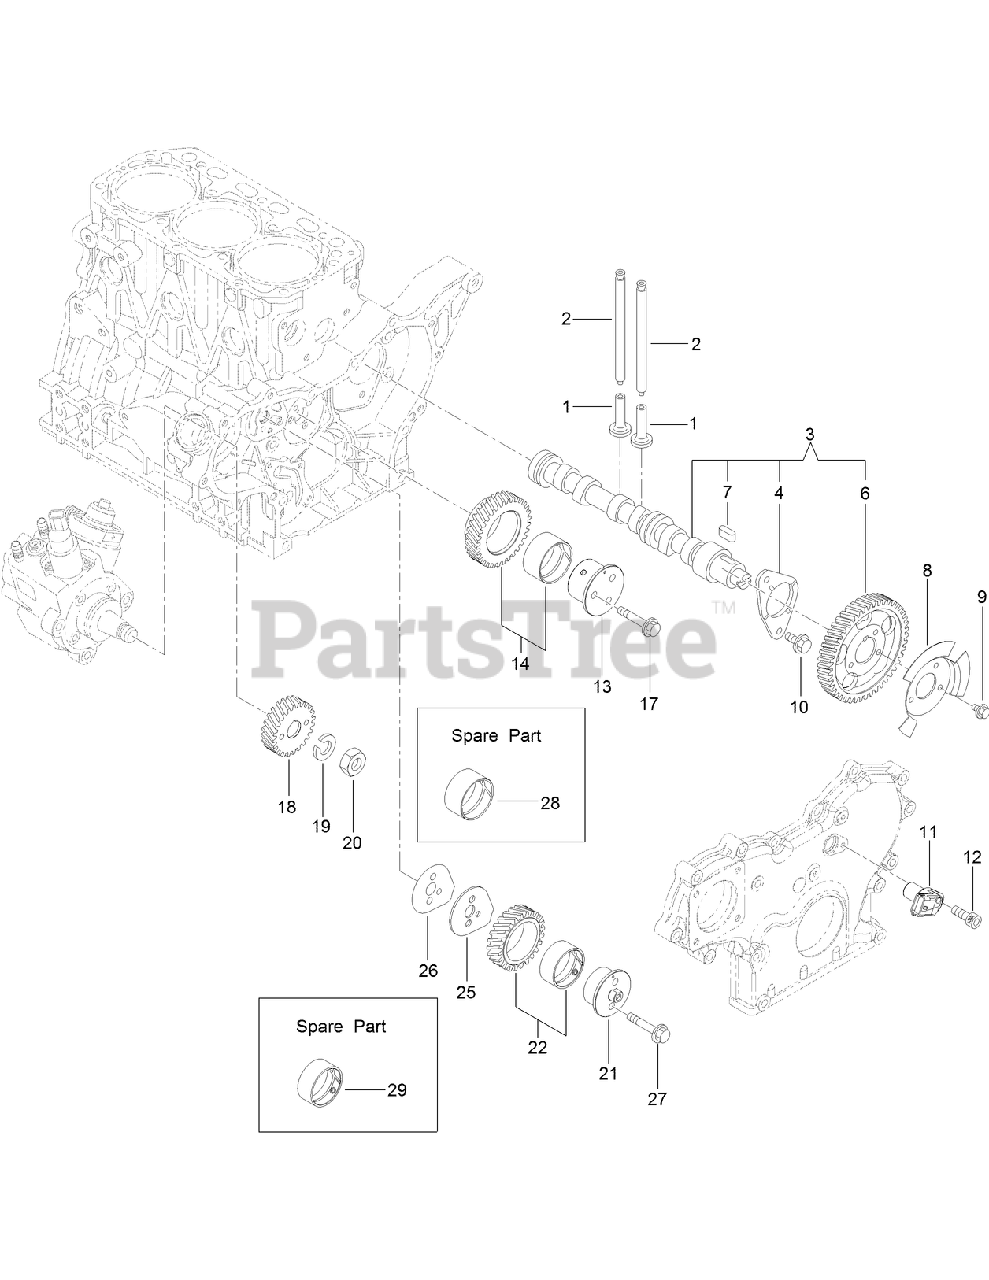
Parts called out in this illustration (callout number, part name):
1	TAPPET
2	ROD-PUSH
3	CAMSHAFT ASM
4	METAL-THRUST
6	GEAR-CAMSHAFT
8	PULSER-CAMSHAFT
11	SENSOR-REV, GEAR
13	SHAFT-IDLE, GEAR A
14	IDLE GEAR A ASM
18	GEAR-PUMP, SUPPLY
19	WASHER-SPRING
20	NUT-LOCK
21	SHAFT-IDLE, GEAR B
22	IDLE GEAR B ASM
25	PLATE-IDLE, SHAFT
26	GASKET-IDLE, SHAFT B
28	BUSHING
29	BUSHING
